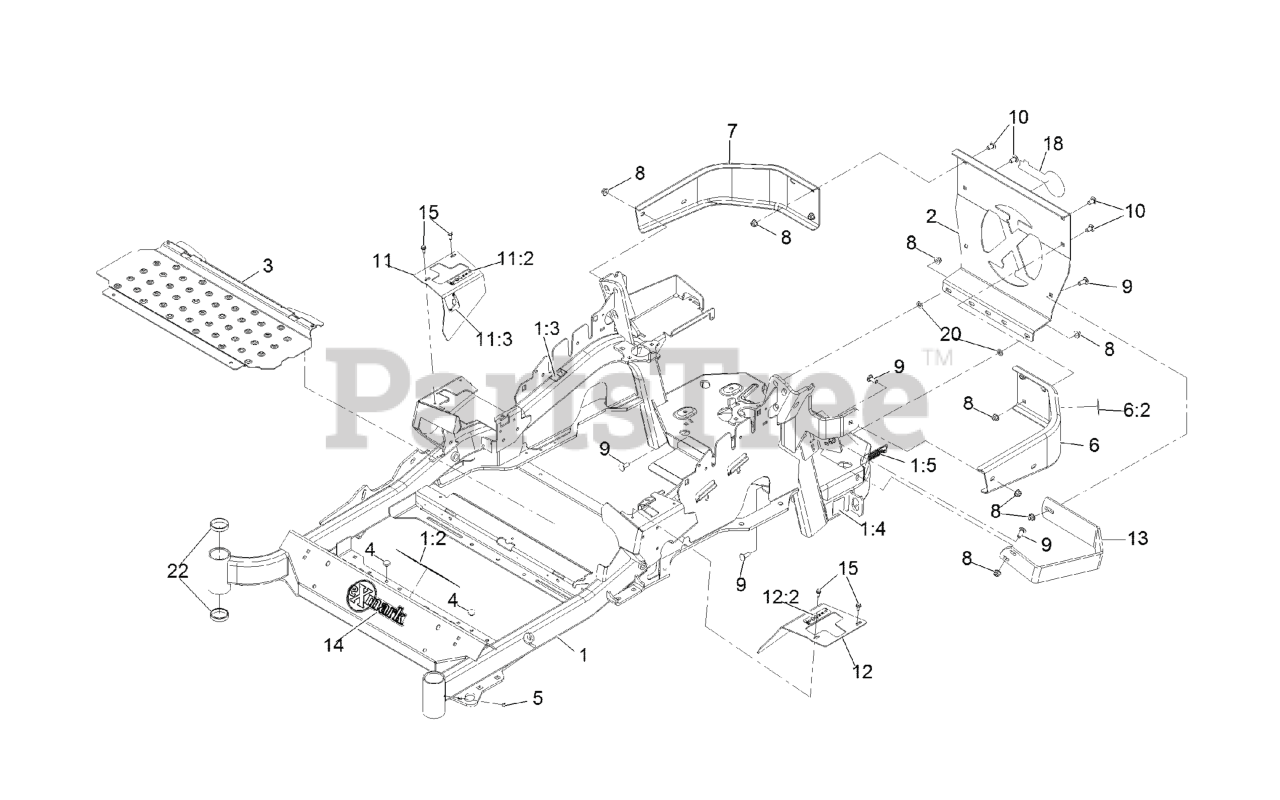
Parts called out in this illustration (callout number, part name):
1	MAINFRAME ASM
1:2	DECAL-DANGER
1:3	DECAL-WARNING
1:4	DECAL-HAZARD, PINCHED FINGER
1:5	DECAL-ARRESTOR, SPARK
2	PLATE,REAR GUARD
6	LH BUMPER ASM
6:2	DECAL-WARNING
7	BUMPER-RH
8	NUT-HF, NI
9	SCREW-CARR
10	SCREW-CARR
11	RH MOTION CONTROL COVER ASM
11:2	DECAL-CONTROL, MOTION
11:3	DECAL-PARK BRAKE, CE
12	LH MOTION CONTROL COVER ASM
12:2	DECAL-CONTROL, MOTION
13	GUARD-MUFFLER
14	DECAL-EXMARK
15	SCREW-HWH
20	NUT-PUSH
22	CUP-BEARING
